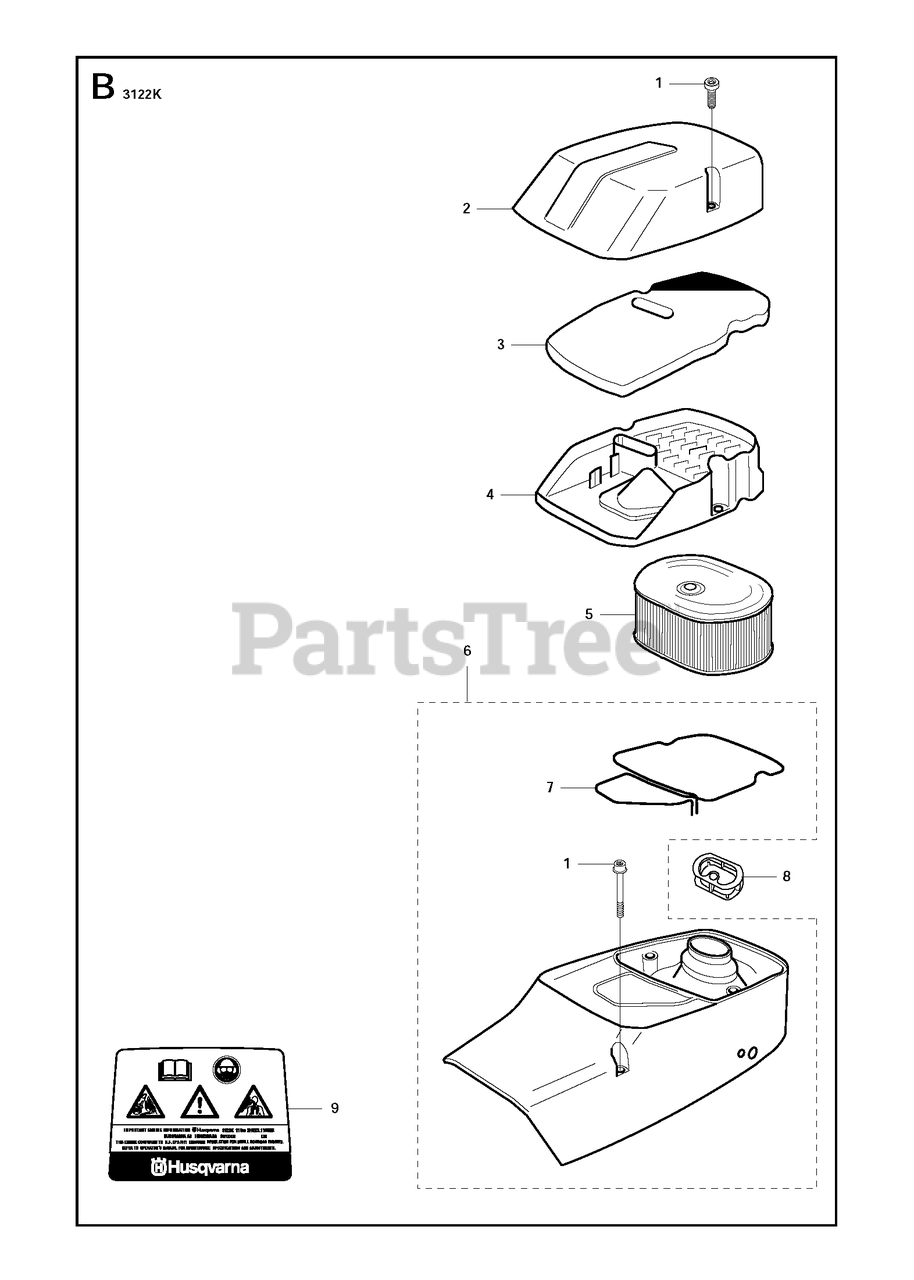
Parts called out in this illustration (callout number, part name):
1	SCREW ITXSCM
2	FILTER COVER
4	FILTER BOTTOM
5	AIR FILTER
6	CYLINDER COVERIncl. 1, 7
